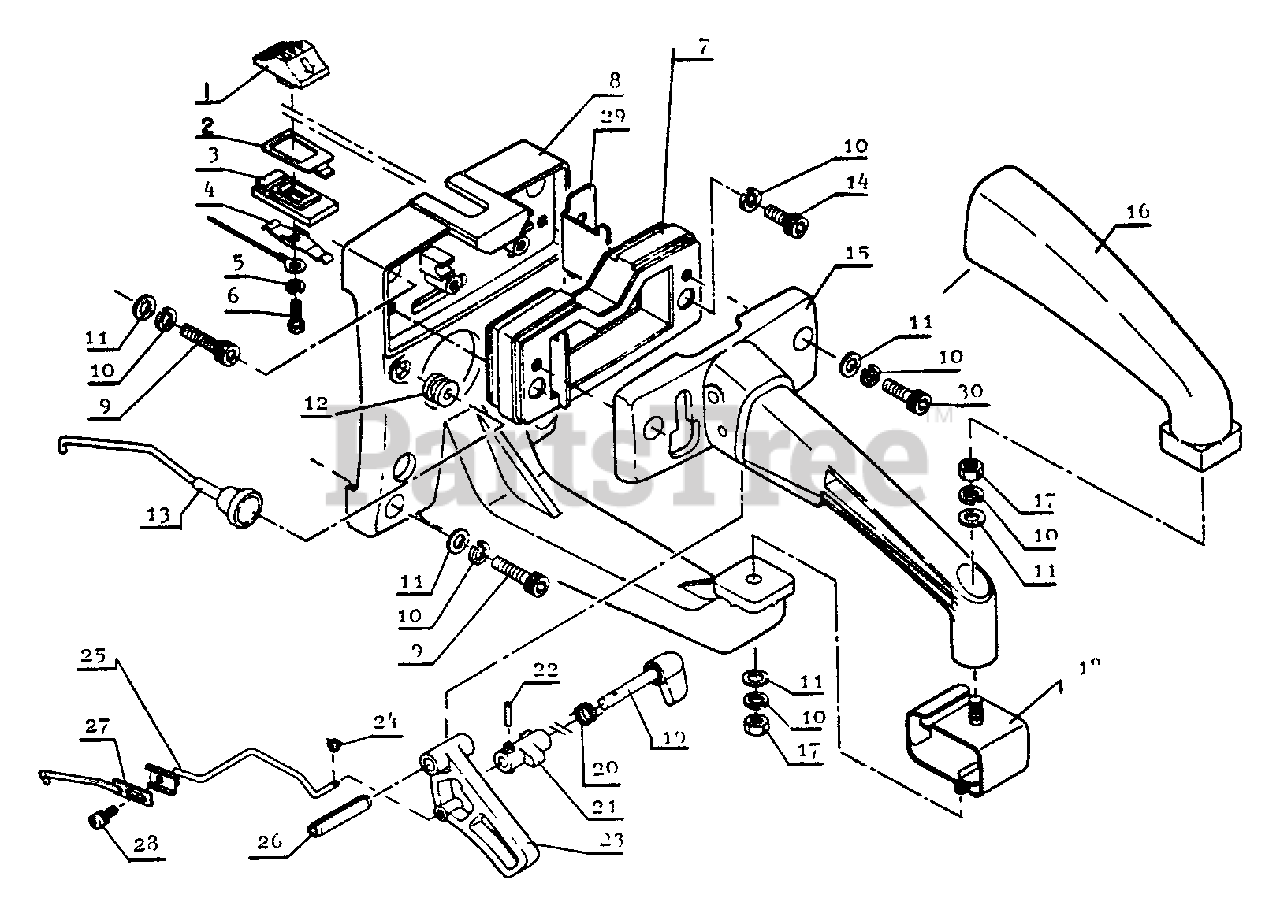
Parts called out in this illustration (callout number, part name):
1	SWITCH, IGNITION
2	PLATE - GROUND
3	PLATE, GUIDE
4	CONTACT, SWITCH
5	WASHER, SPRING 4 MM
6	SCREW 4×10
7	CUSHION
8	REAR HANDLE SUPPORTER
9	BOLT 5×20
10	WASHER, SPRING 5
11	WASHER
12	GROMMET, RUBBER
13	ROD, CHOKE
14	BOLT M5×10
15	HANDLE - REAR
16	GRIP, REAR HANDLE
17	LOCKNUT - 5
18	CUSHION
19	LEVER, THROTTLE
20	SPRING, THROTTLE LOCK
21	LOCKOUT, TRIGGER
22	PIN, SPRING 16×10
23	TRIGGER, THROTTLE
24	PIN
25	ROD, THROTTLE - A
26	PIN
27	ROD, THROTTLE - B
28	SCREW - 3×6
29	BRACKET
30	SCREW - 5×15
